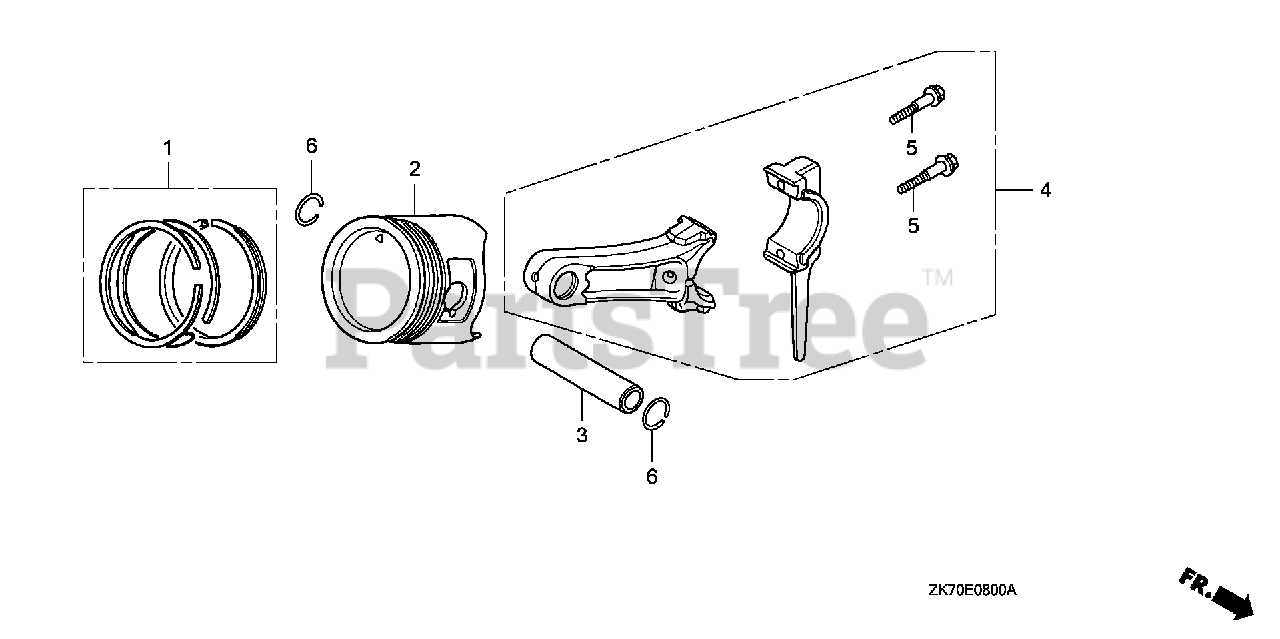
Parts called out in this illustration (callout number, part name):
1	RING SET, PISTON (STD) (NIPPON)
1	RING SET, PISTON (STD) (TEIKOKU)
1	RING SET, PISTON (OS 0.25) (Honda Code 7066400). (TEIKOKU)
1	RING SET, PISTON (OS 0.25) (Honda Code 7066418). (NIPPON)
1	RING SET, PISTON (0.25) (TEIKOKU)
1	RING SET, PISTON (OS 0.50) (Honda Code 7066426). (TEIKOKU)
1	RING SET, PISTON (OS 0.50) (Honda Code 7066434). (NIPPON)
1	RING SET, PISTON (0.50) (TEIKOKU)
1	RING SET, PISTON (0.75) (Honda Code 7066442). (TEIKOKU)
1	RING SET, PISTON (0.75) (Honda Code 7066459). (NIPPON)
1	RING SET, PISTON (0.75) (TEIKOKU)
2	PISTON (STD)
2	PISTON (OS 0.25) Use up to Engine SN 3993725.
2	PISTON (0.25)
2	PISTON (OVER SIZE) (0.50) Use from Engine SN 3993726.
2	PISTON (0.50)
2	PISTON (0.75) Use up to Engine SN 3993725.
2	PISTON (0.75)
3	PIN, PISTON
4	ROD ASSY., CONNECTING
5	BOLT, CONNECTING ROD
6	CLIP, PISTON PIN (13MM)
